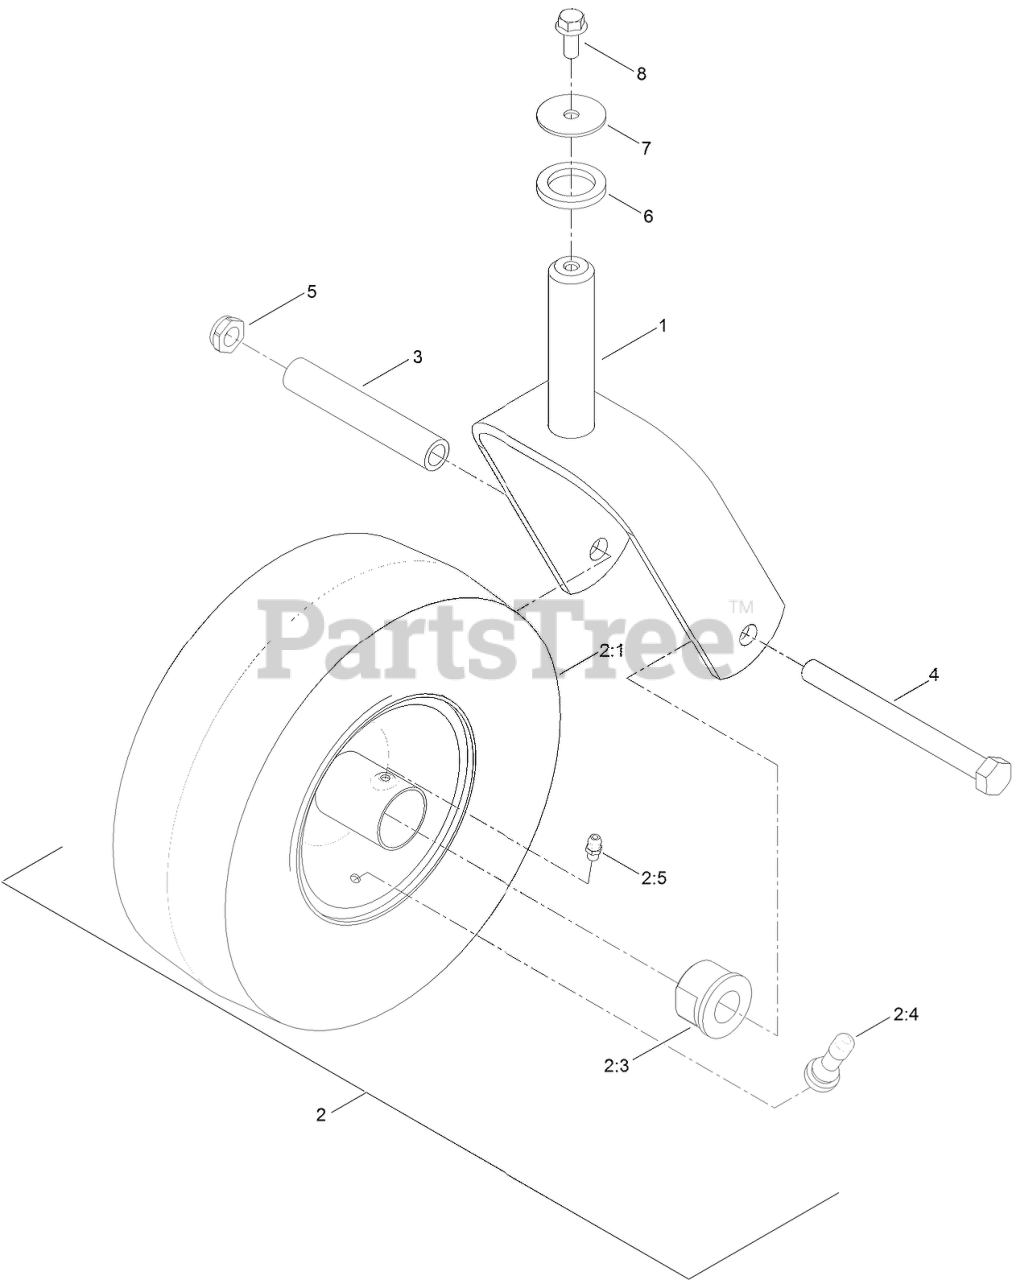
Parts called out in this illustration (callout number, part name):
1	CASTER FORK ASM
2	CASTER WHEEL ASM
2:3	BUSHING-FLANGE
2:5	FITTING-GREASE
2:6	TUBE-INNER
3	BUSHING-SPANNER
4	SCREW-HH
5	NUT-HEX
6	WASHER-THRUST
7	WASHER-FLAT
8	SCREW-HHF
